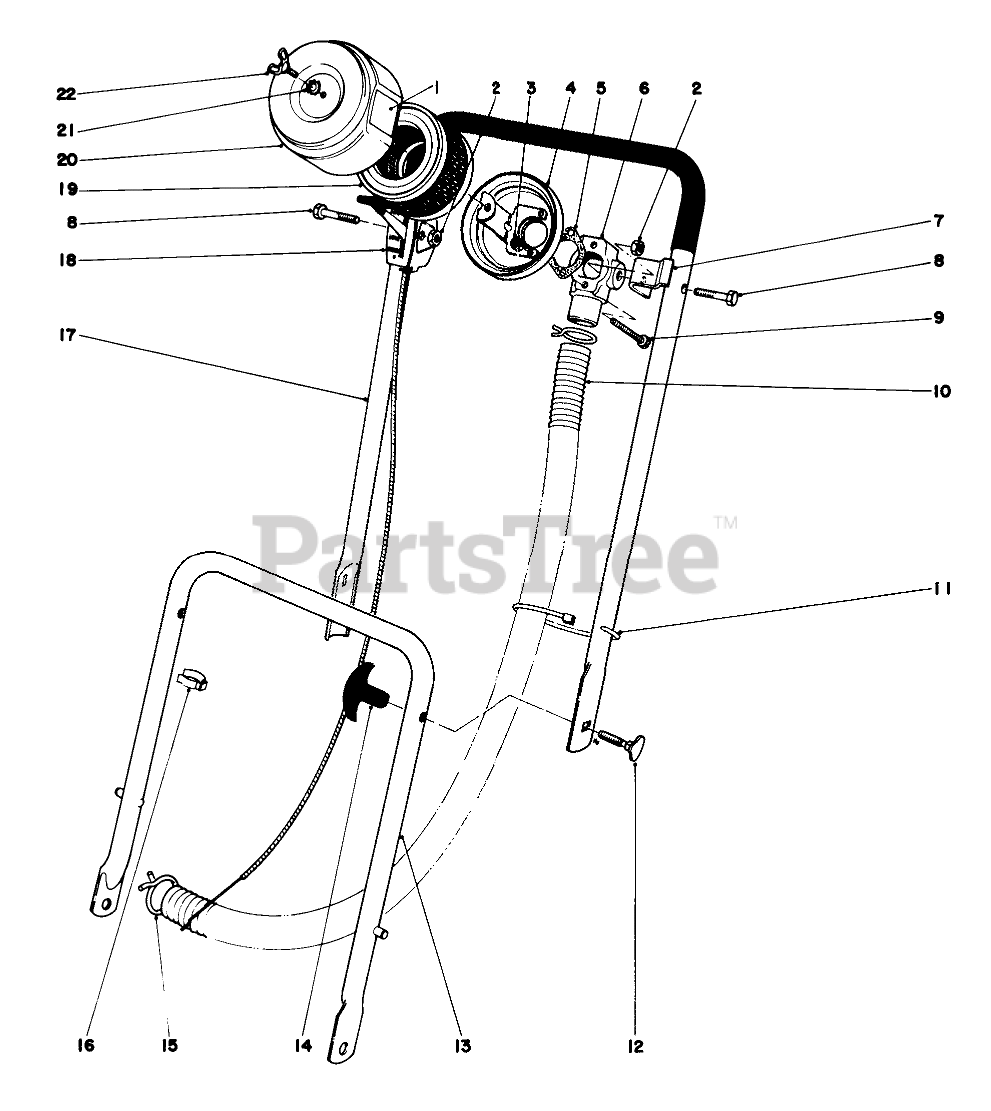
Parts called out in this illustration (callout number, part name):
1	Air Cleaner Decal
2	NUT-LOCK, CONE
3	Locknut
4	Air Cleaner Pan
5	Gasket
7	Support Air Cleaner
8	SCREW-HH
9	Slotted Hex Hd. Machine Screw
10	Air Cleaner Hose
11	TIE-CABLE
12	HANDLE SCREW
13	Lower Handle
15	CLAMP
16	BOWDEN CLIP
17	Handle Upper
18	THROTTLE CONTROL
19	Air Cleaner Element
20	Air Cleaner Cover
21	WASHER-LOCK, EXT
22	Wing Screw
